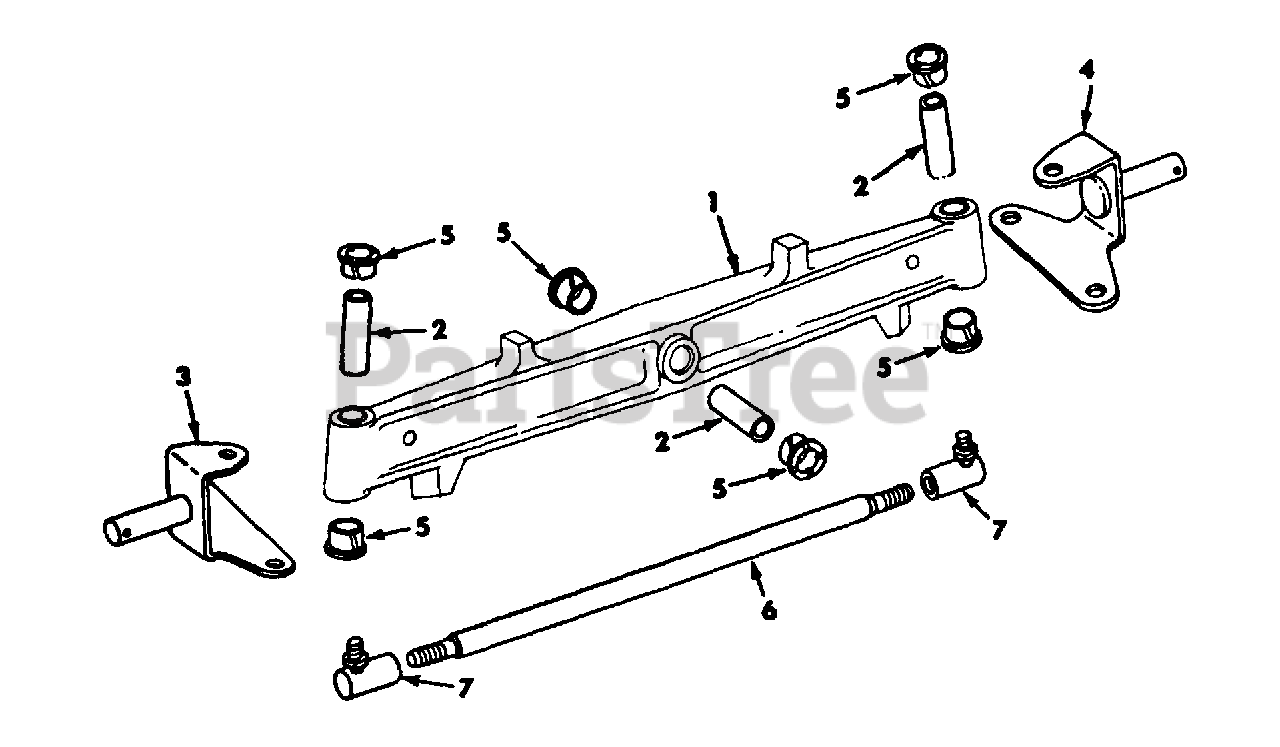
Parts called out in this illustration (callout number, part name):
1	AXLE, FRONT
2	BUSHING, FRONT AXLE
3	ARM ASSY, SPINDLE RH
4	ARM ASSY, SPINDLE LH
5	BEARING, FRONT AXLE
7	JOINT, 3/8-24 TIE ROD BALL
